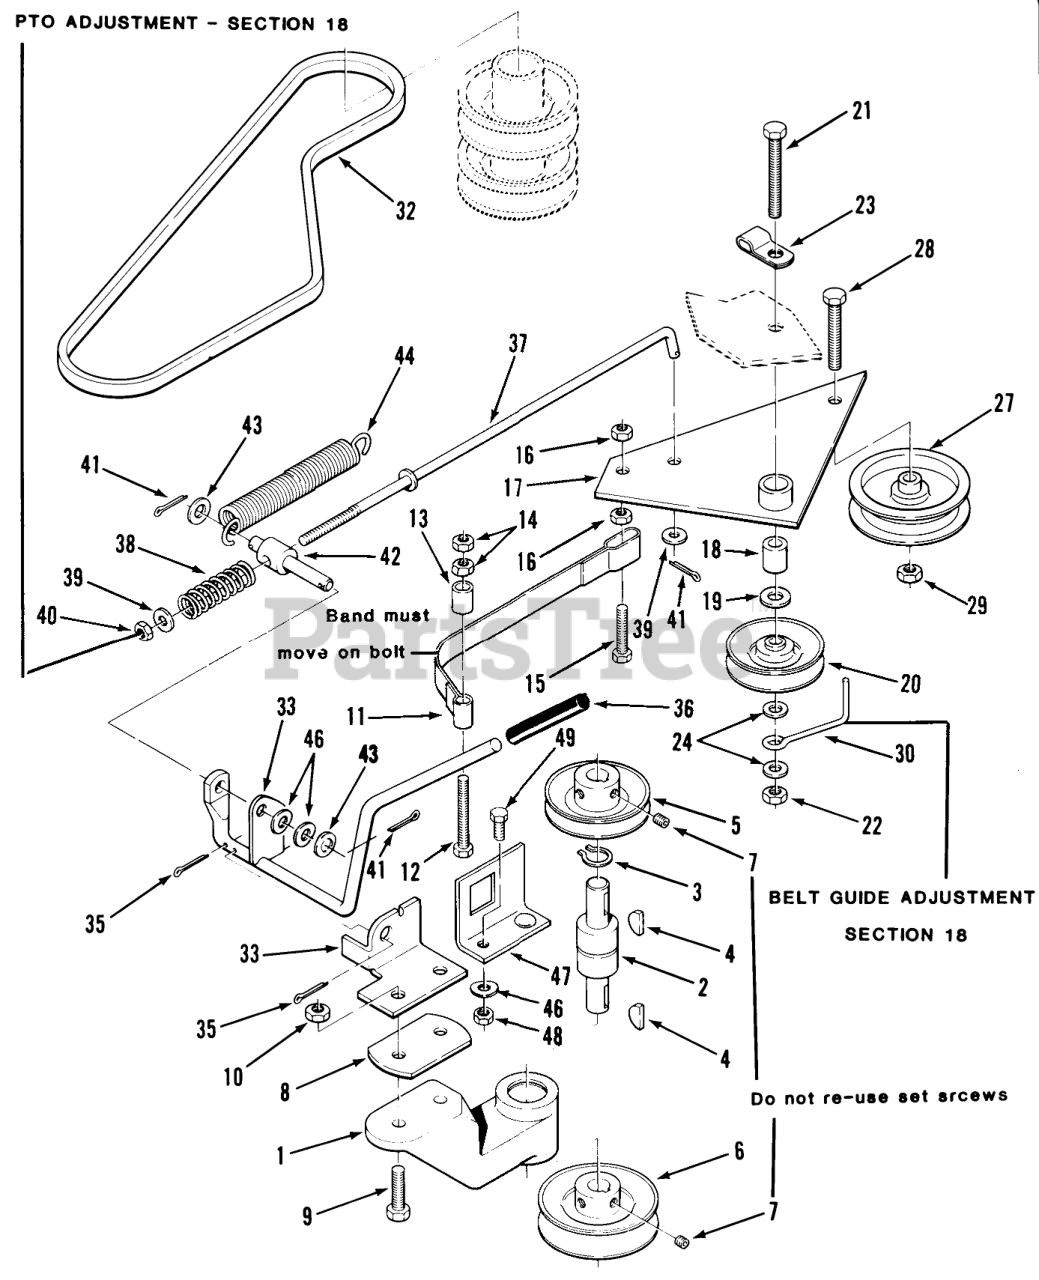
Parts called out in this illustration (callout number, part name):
1	Jack Shaft Housing
2	BEARING-INT SHAFT
3	Snap Ring
4	KEY-WOODRUFF
5	PULLEY
6	PULLEY
7	Set Screw
8	PLATE SPACER R
9	Bolt
10	NUT
11	PT0 Brake Band
12	BOLT 5/16-18X2 1/4
13	SPACER
14	Nut
15	Bolt
16	Nut
17	ASSY LEVER BLADE DRI
18	SPACER
19	Washer
20	IDLER PULLEY R
21	Bolt
22	NUT
23	CLAMP DOUBLE
24	Washer
27	Flat Idler
28	Bolt
29	NUT-HEX, JAM
30	RETAINER-BELT
32	V-BELT
33	HANDLE PTO CLUTCH R
35	Cotter Pin
36	GRIP
37	PT0 Handle To Lever Rod
38	SPRING-CLUTCH
39	WASHER 5/16 SAE
40	Nut
41	Cotter Pin
42	TRUNNION
43	Washer
44	SPRING R
46	WASHER-SPRING
47	ASSY BRACKET SWIT R
48	Nut
49	H H C S
